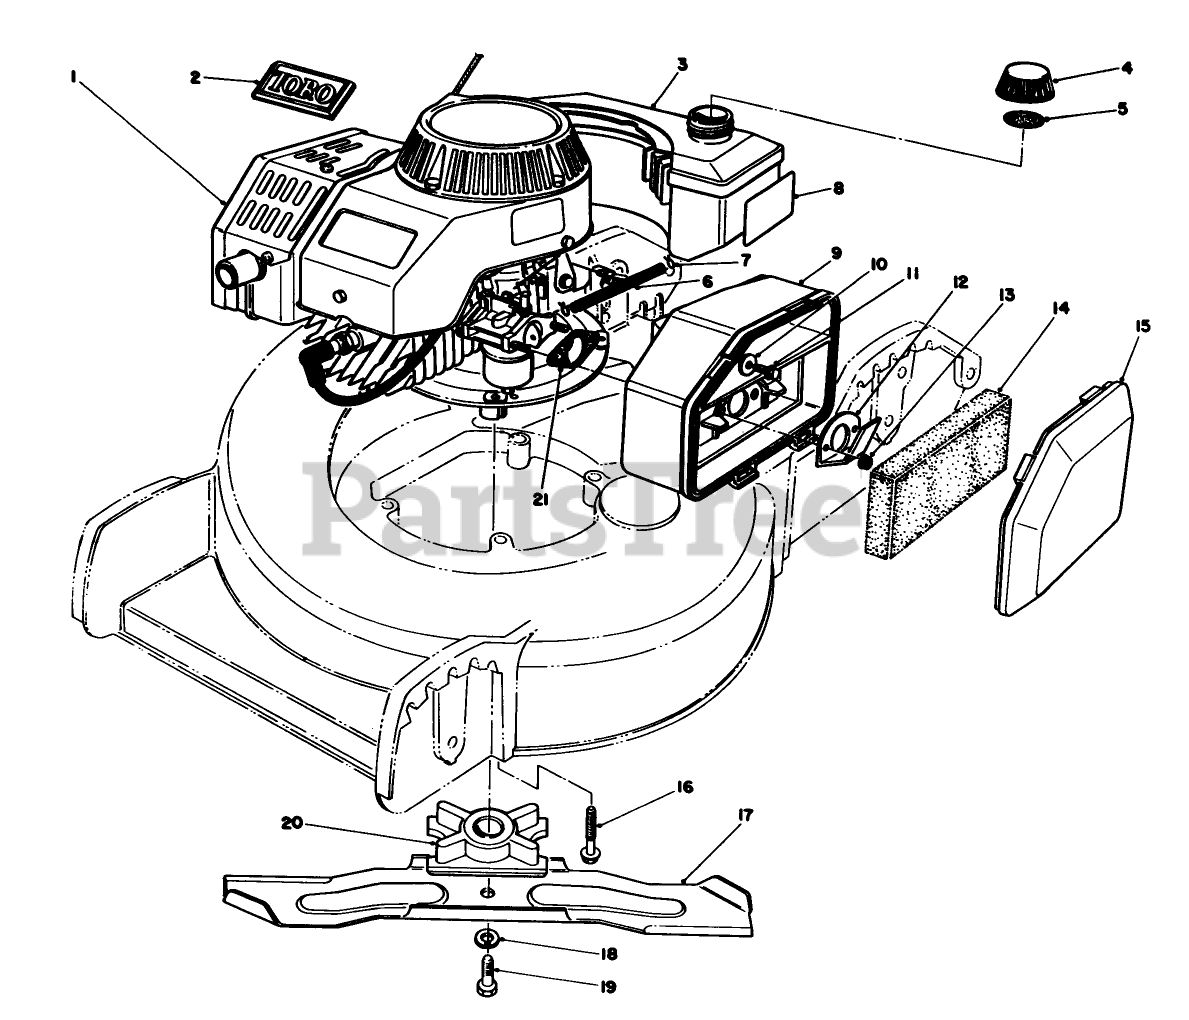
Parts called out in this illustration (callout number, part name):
4	GAS CAP ASM 50:1
5	GAS CAP GASKET
6	FUEL LINE
7	CLAMP-HOSE
9	AIR CLEANER
10	WASHER-FLAT
11	SCREW-HH
12	SPIT BACK DEFLECTOR
14	FILTER
16	SCREW-HHF
18	WASHER-LOCK
19	SCREW-HH
20	BLADE RETAINER
21	GASKET-AIR CLEANER
